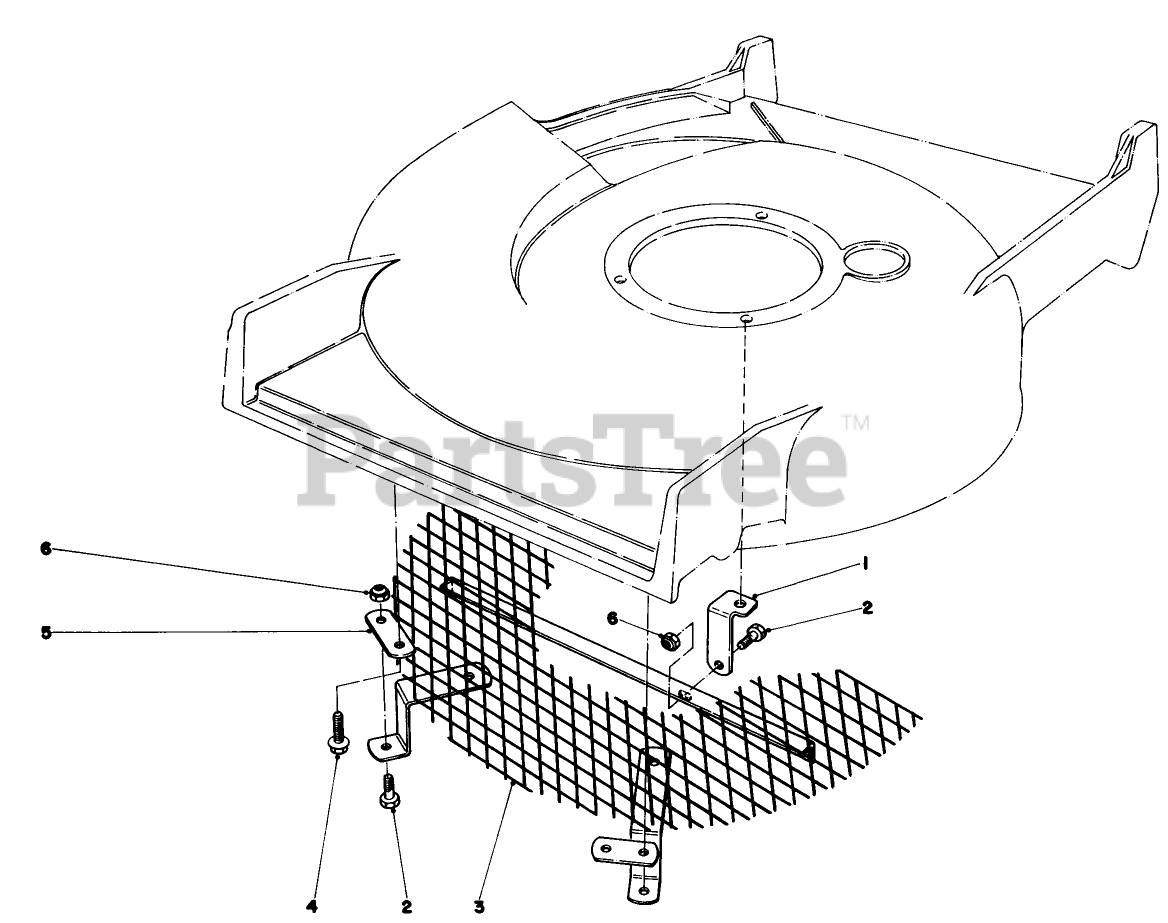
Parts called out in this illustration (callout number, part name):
2	SCREW-HH
4	SCREW-THD ROLL, HWH
6	NUT-LOCK, NI
